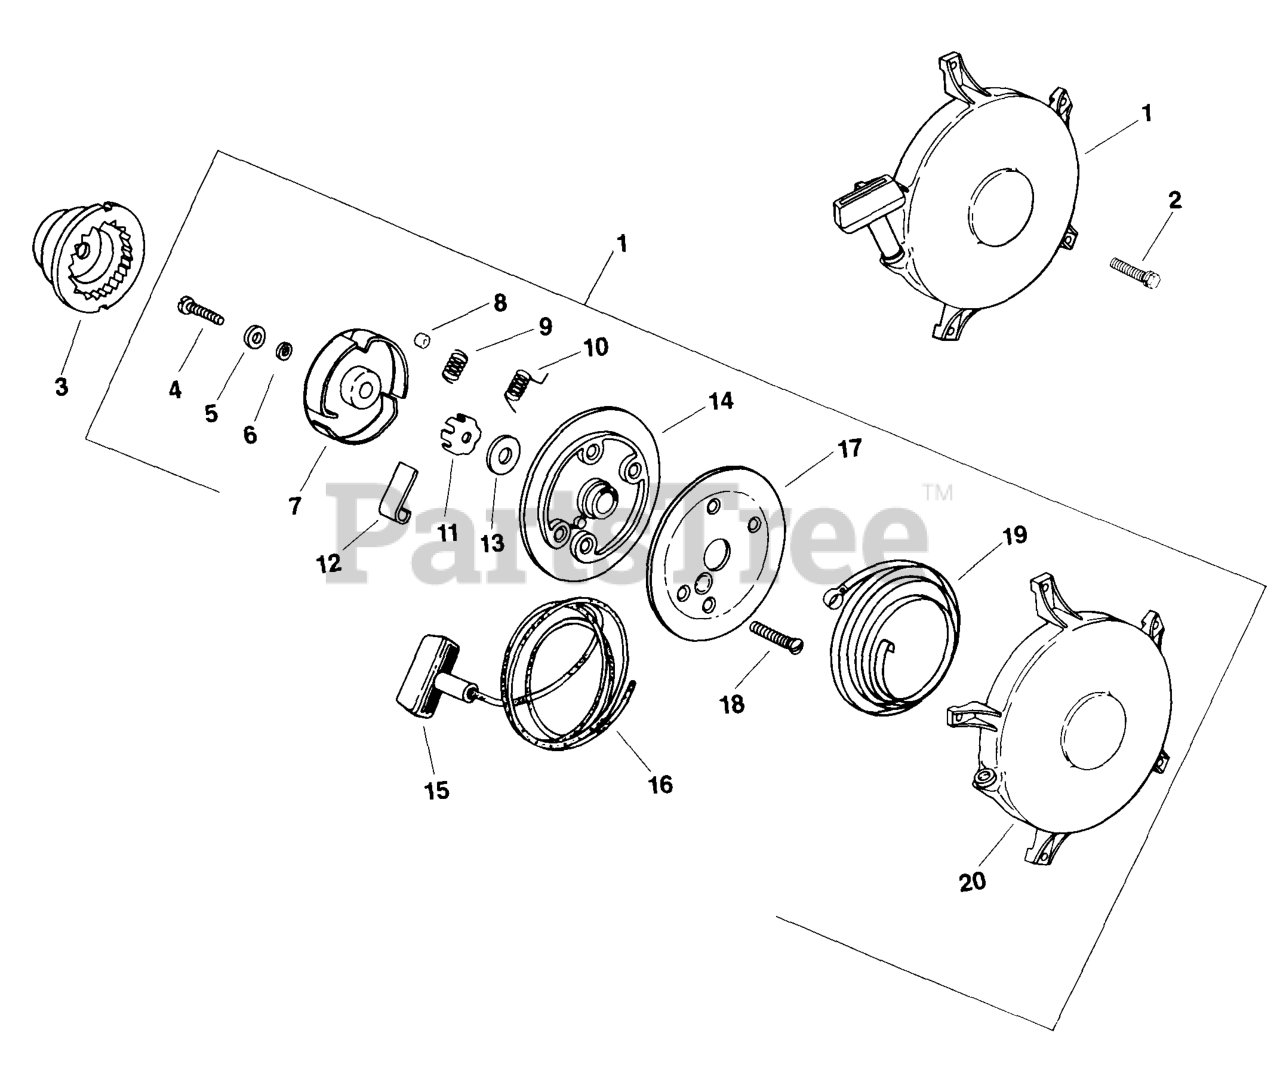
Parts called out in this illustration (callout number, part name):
1	STARTER
3	CUP, DRIVE - DISCONTINUED
5	WASHER - DISCONTINUED
7	RETAINER
8	SPACER
9	SPRING - DISCONTINUED
12	DOGS - DISCONTINUED
15	HANDLE - USE 25 166 01
20	HOUSING - DISCONTINUED
